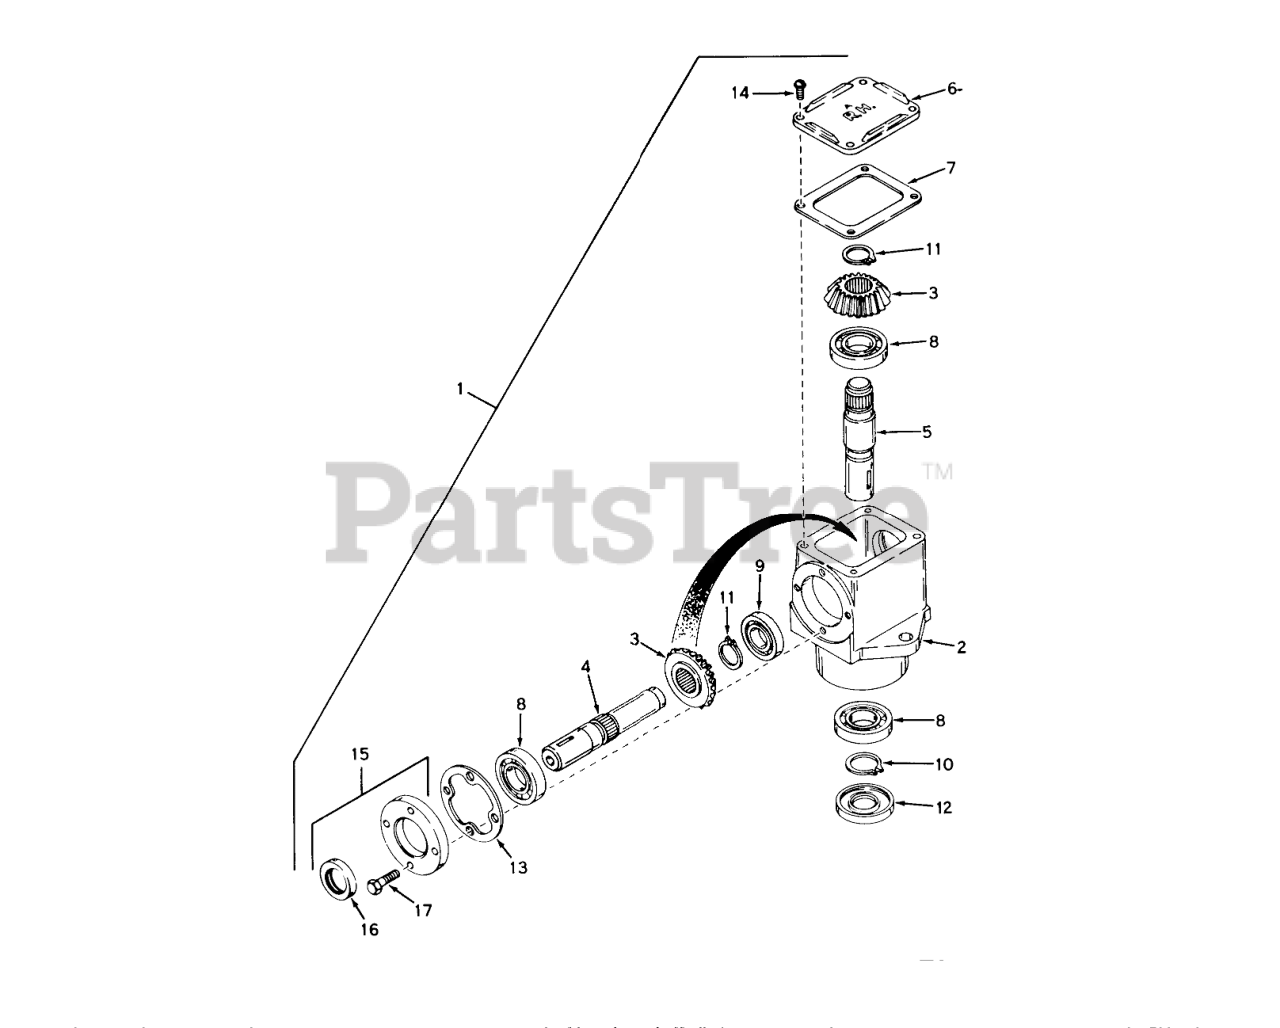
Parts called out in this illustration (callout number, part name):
1	Head Assy., Right Hand (Incl. Nos. 2 thru 15)
2	Housing, Right Angle Drive
3	Bevel Gear
4	Shaft, Input Pinion
5	Shaft, Output
6	Cover, Right Hand
7	Gasket
8	Bearing
9	Bearing
10	Ring-Snap
11	Ring-Snap
13	Gasket
15	Cap & Seal Assy., Retainer (Incl. Nos. 16 & 17)
16	Oil Seal
